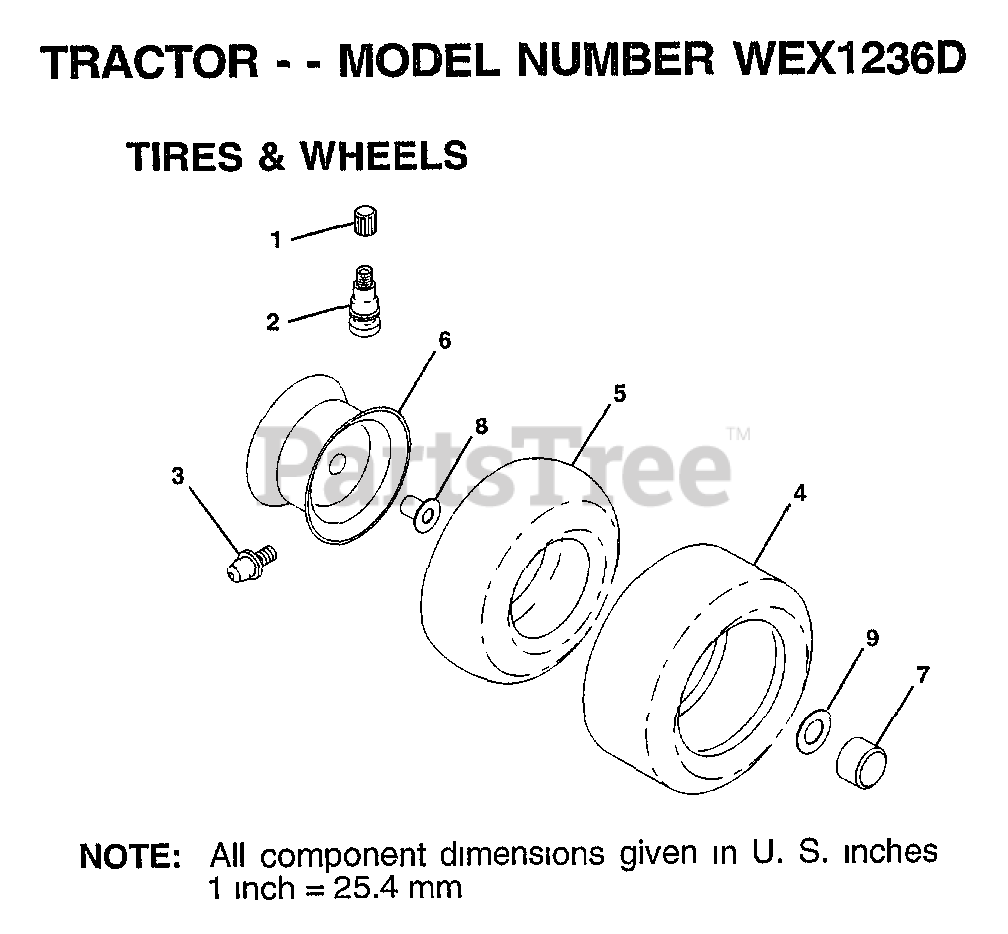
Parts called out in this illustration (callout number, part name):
1	VALVE CAP
2	VALVE STEM LT
3	FITTING LT
5	TUBE.5.3/4.5/6
5	TUBE.16X6.5/7.5-8
6	"RIM FRONT 6"""
6	"RIM ASM REAR 8"""
7	HUB CAP
8	"FLANGE, BEARING"
9	WASHER
